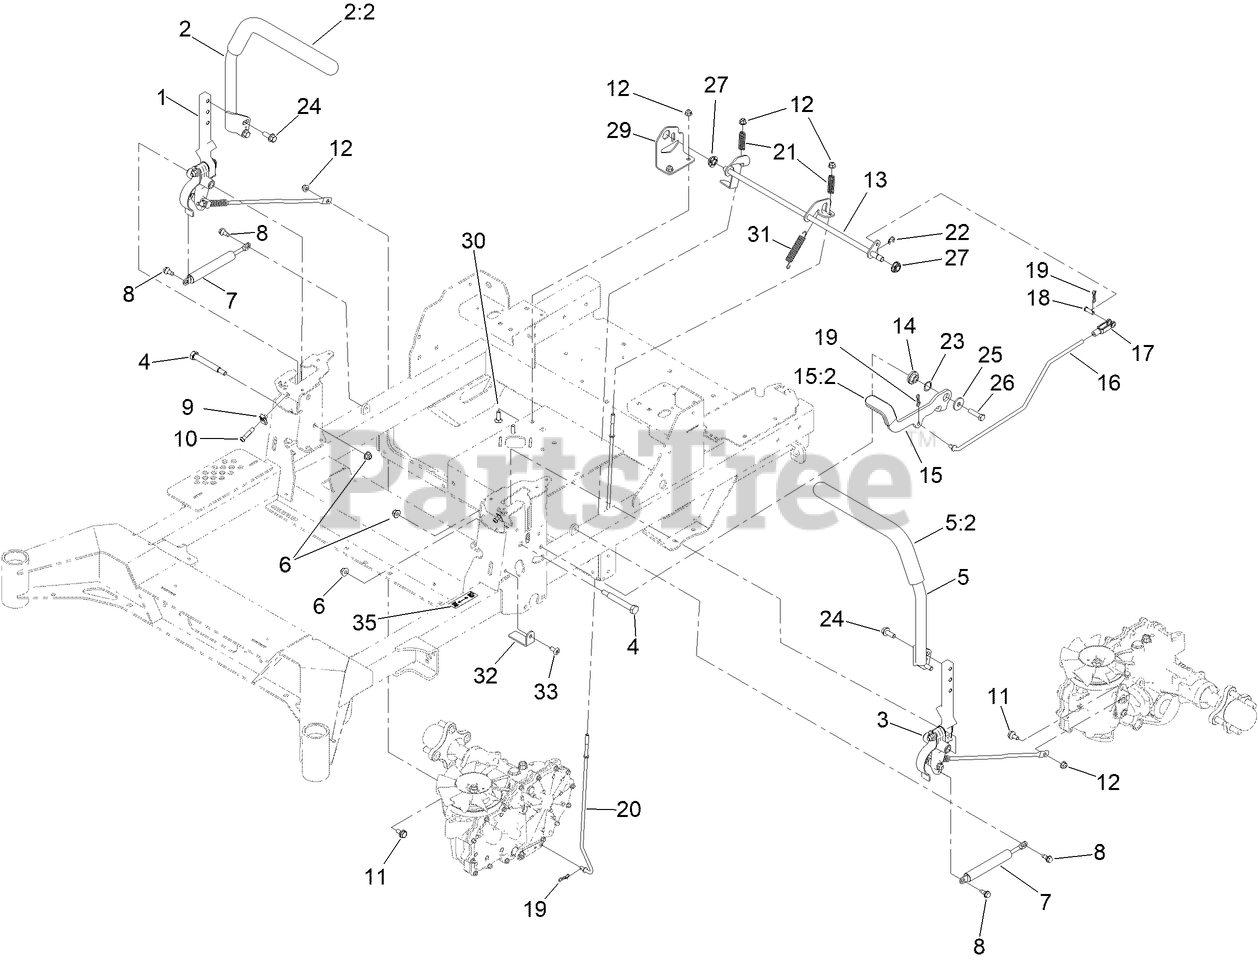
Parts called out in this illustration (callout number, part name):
1	MOTION CONTROL ASM-RH
2	HANDLE ASM - RH
2:2	GRIP-CONTROL, LEVER
3	MOTION CONTROL ASM-LH
4	BOLT-PIVOT
5	HANDLE ASM - LH
5:2	GRIP-CONTROL, LEVER
6	NUT-HF, NI
7	DAMPER
8	SCREW-SHOULDER
10	SCREW-HSBH
11	BOLT-SHOULDER,HFH
12	NUT-HF, NI
13	SHAFT-BRAKE
14	PIVOT-FLANGE
15	LEVER-BRAKE
15:2	GRIP-LEVER
16	LINKAGE-BRAKE, UPPER
17	YOKE-ADJUSTABLE
18	PIN-CLEVIS
19	PIN-COTTER, LOCKING
20	LINKAGE-BRAKE, LOWER
21	SPRING-COMPRESSION
22	RING-RETAINING, EXTERNAL
23	WASHER-WAVE
24	SCREW-HHF
25	WASHER
26	SCREW-HH
27	BEARING-SPHERICAL
29	BRACKET-BRAKE
30	SCREW-CARR
31	SPRING-EXTENSION
32	PLATE-STOP, RTN
35	DECAL-BRAKE, PARKING
